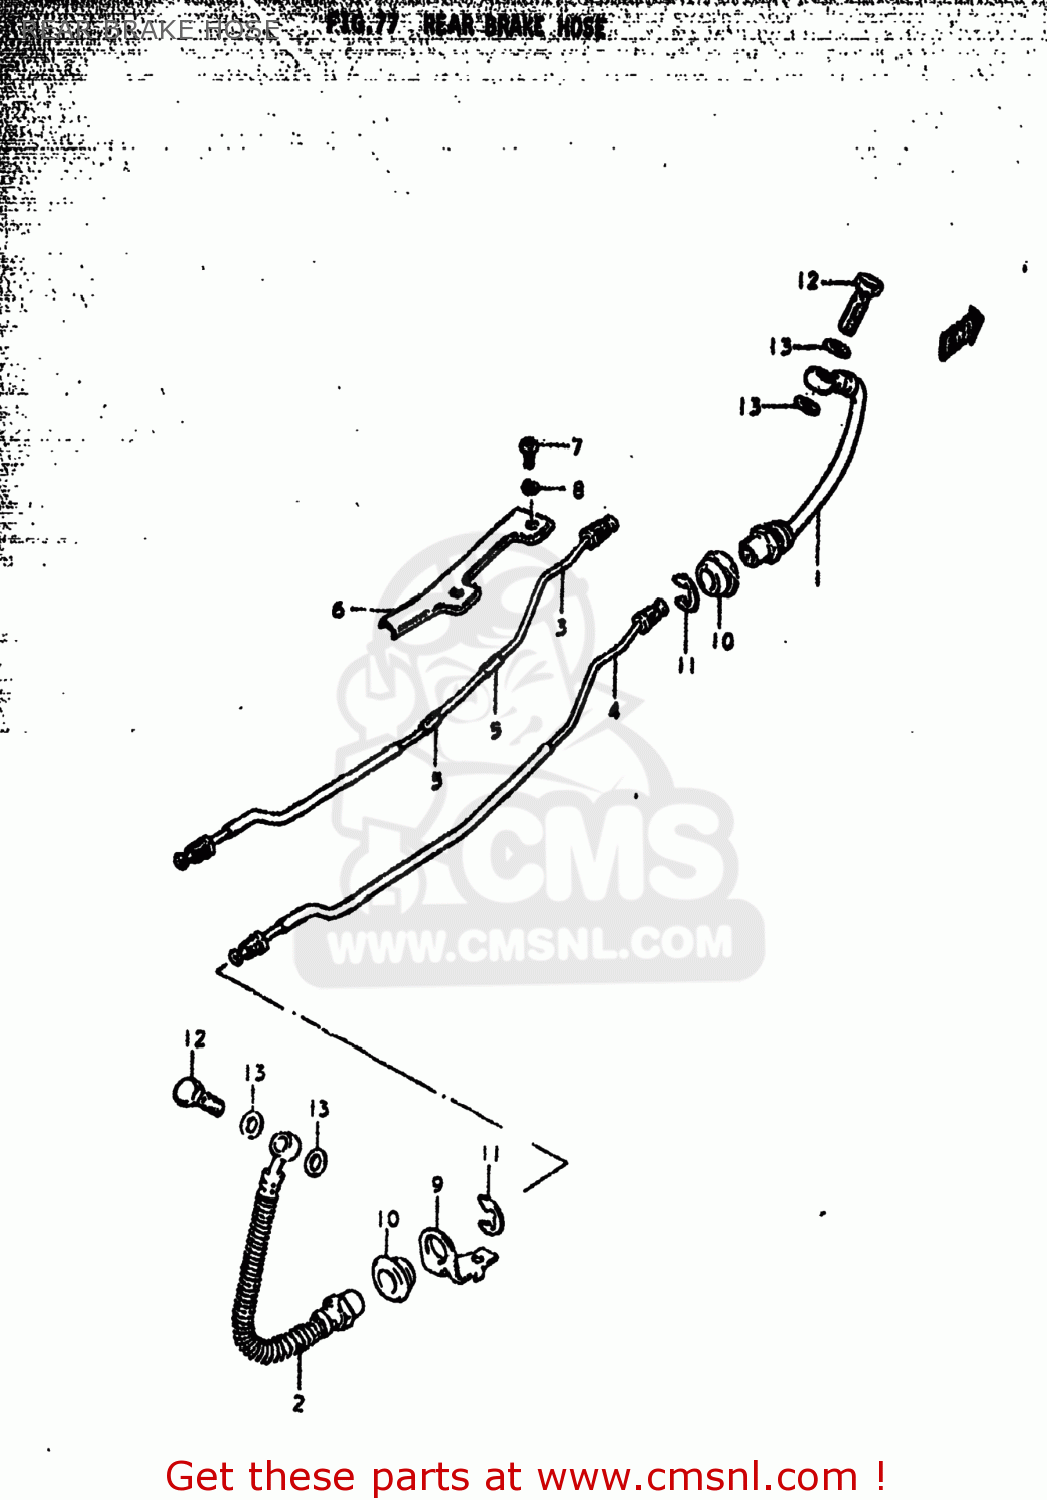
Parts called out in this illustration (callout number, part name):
1	HOSE,REAR BRAKE NO.1
2	HOSE,RR BRAKE NO.2
3	PIPE,REAR BRAKE
4	PIPE,REAR BRAKE
5	PROTECTOR,BRAKE
6	COVER,REAR BRAKE PIPE
7	BOLT(6X8)
8	LOCK WASHER
9	GUIDE,BRAKE HOSE
10	GROMMET,BRAKE HOSE GUIDE
11	E RING
12	BOLT UNION
13	WASHER
